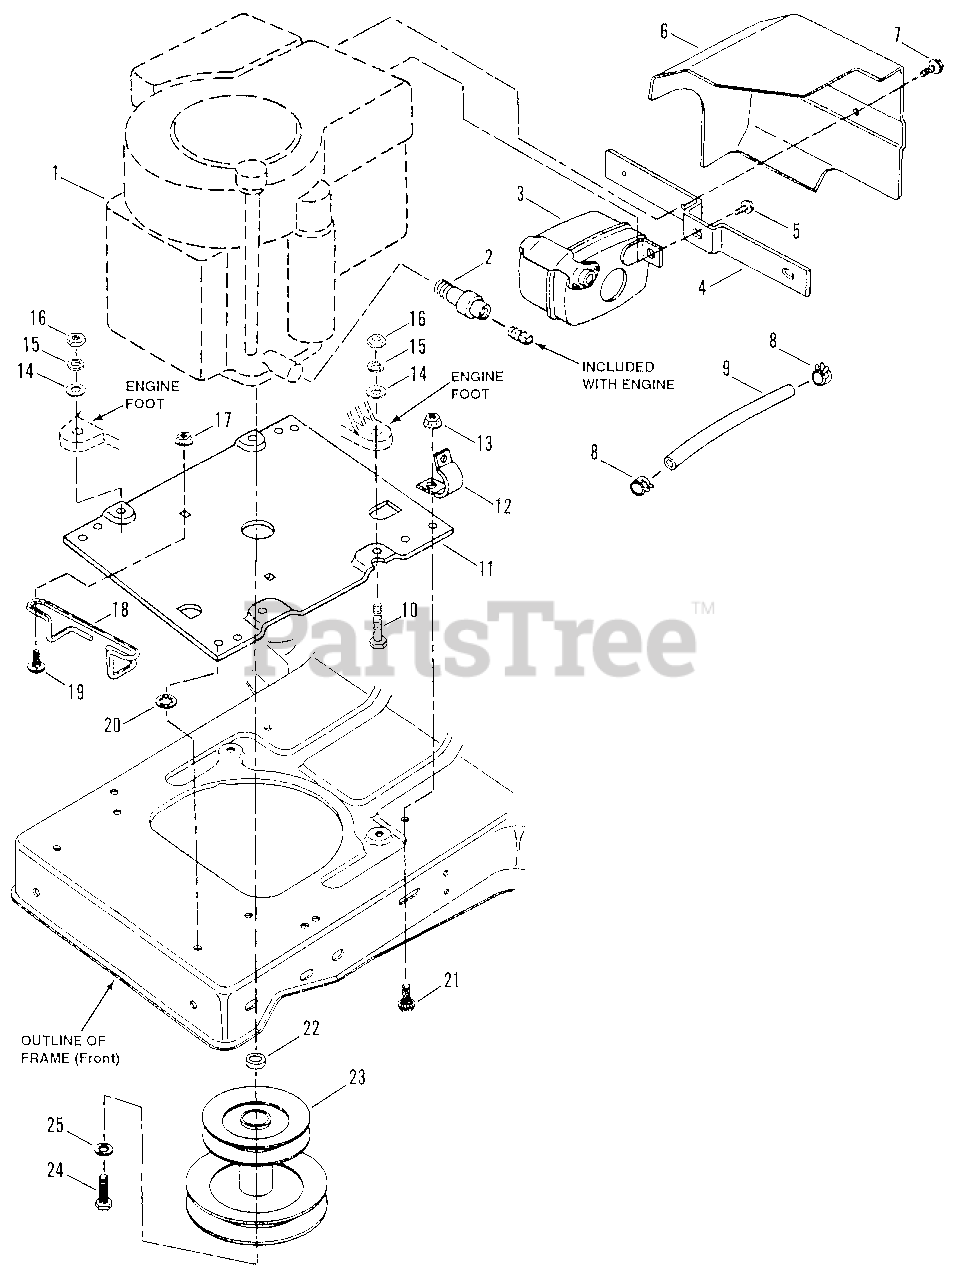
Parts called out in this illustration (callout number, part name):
1	* ENGINE, B&S, 12 HP Mod. 283707-0134-02 (38" Model)
2	EXTENSION, Oil Drain (Short)
3	MUFFLER, Exhaust
4	BRACKET, Heat Shield
5	BOLT, 1/4-20 x 1/2" Hex Flg. Lk.
6	HEAT SHIELD
7	SCREW, #10-24 x 1/2" Hex Washer Head, Self-Tapping
8	CLAMP, Fuel Line
9	LINE, Fuel, 7" Long
10	SCREW, 5/16-18 x 1 1/2" Hx. Hd.
11	SUB-PLATE, Engine
12	CLIP, Harness
13	NUT, 5/16-18 Hex Flg. Lk.
14	WASHER, 5/16 Flat
15	WASHER, 5/16 Split Lock
16	NUT, 5/16-18 Hex
17	NUT, 1/4-20 Hex Flange Lk.
18	GUIDE, Belt
19	BOLT, 1/4-20 x 5/8" Short Neck Carriage, Grade 5
20	WASHER, 5/16 Int. Tooth Lock
21	BOLT, 5/16-18 x 1" Hex Flange Lock
23	PULLEY ASSEMBLY
24	BOLT, 7/16-20 x 1 1/2" Grade 5
25	WASHER, 7/16 Split Lock
